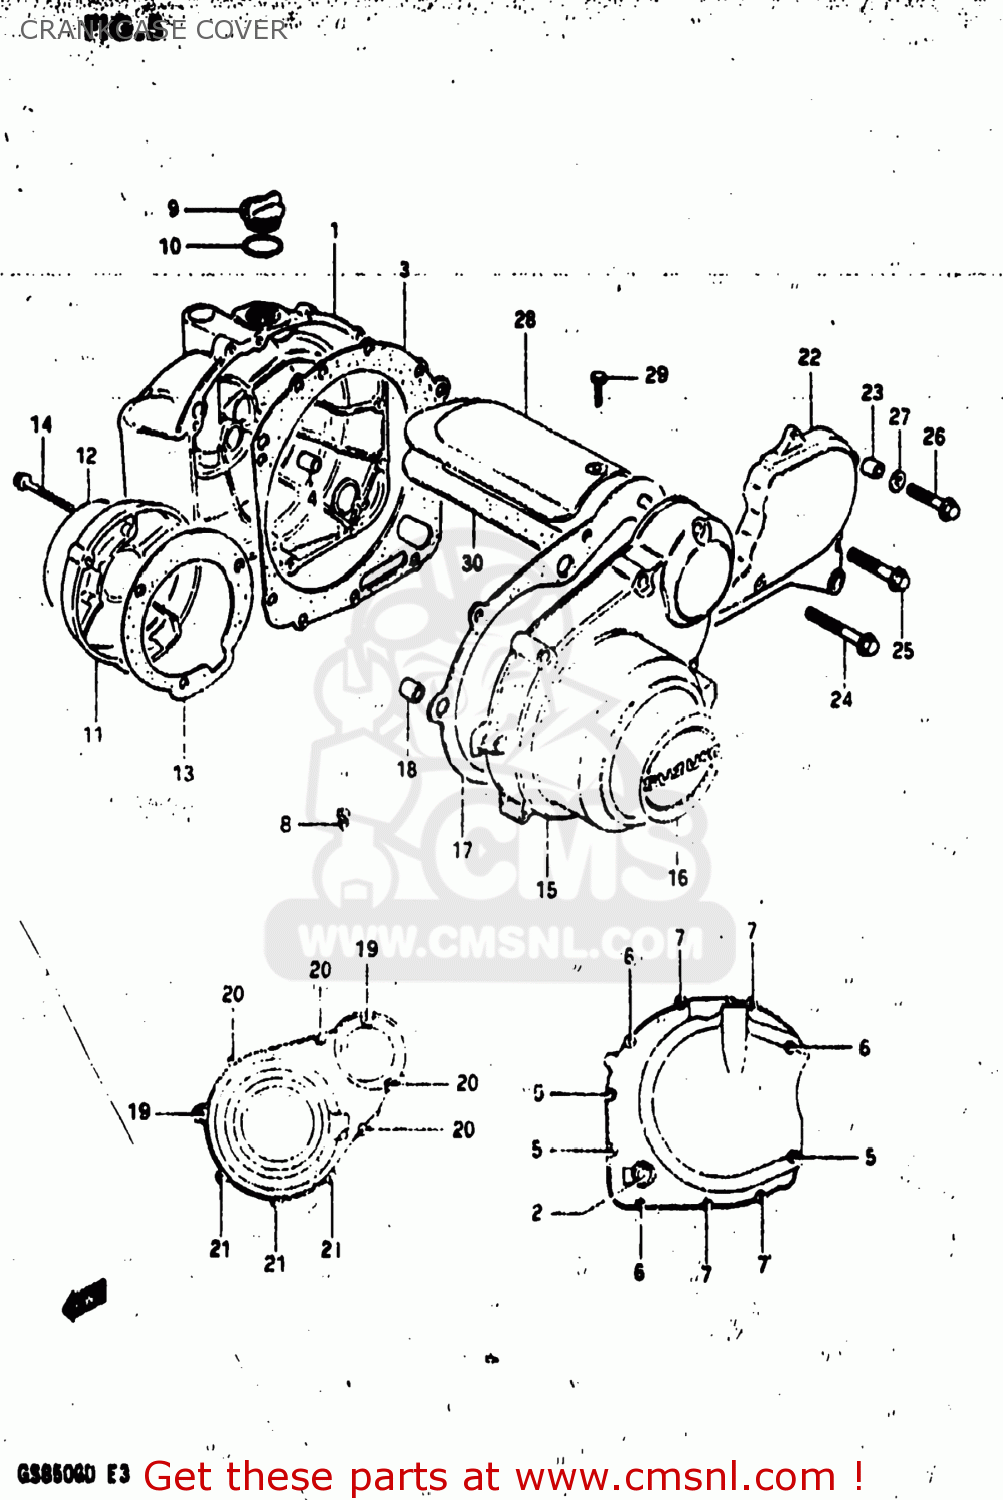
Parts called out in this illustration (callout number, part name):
1	COVER,CLUTCH
2	LENS,OIL LEVEL CHECK
3	GASKET,MAGNETO COVER (N (MCA)
4	PIN
5	BOLT (6X35)
6	BOLT (6X30)
7	BOLT
8	JET
9	CAP
10	O RING(D:2.2,ID:32)
11	COVER,CONTACT BREAKER
12	EMBLEM,CONTACT BREAKER COVER
13	GASKET,CONTACT BREAKER COVER (NAS)
14	BOLT (5X30)
15	COVER,MAGNETO
16	EMBLEM,MAGNETO COVER
17	GASKET,MAGNETO COVER (MCA)
18	PIN
19	BOLT
20	BOLT (6X40)
21	BOLT (6X35)
22	COVER,SPROCKET
23	PIN
24	BOLT (6X30)
25	BOLT (6X20)
26	BOLT
27	WASHER
28	COVER,STARTER MOTOR
29	BOLT
30	GASKET,STARTER MOTOR COVER (MCA)
